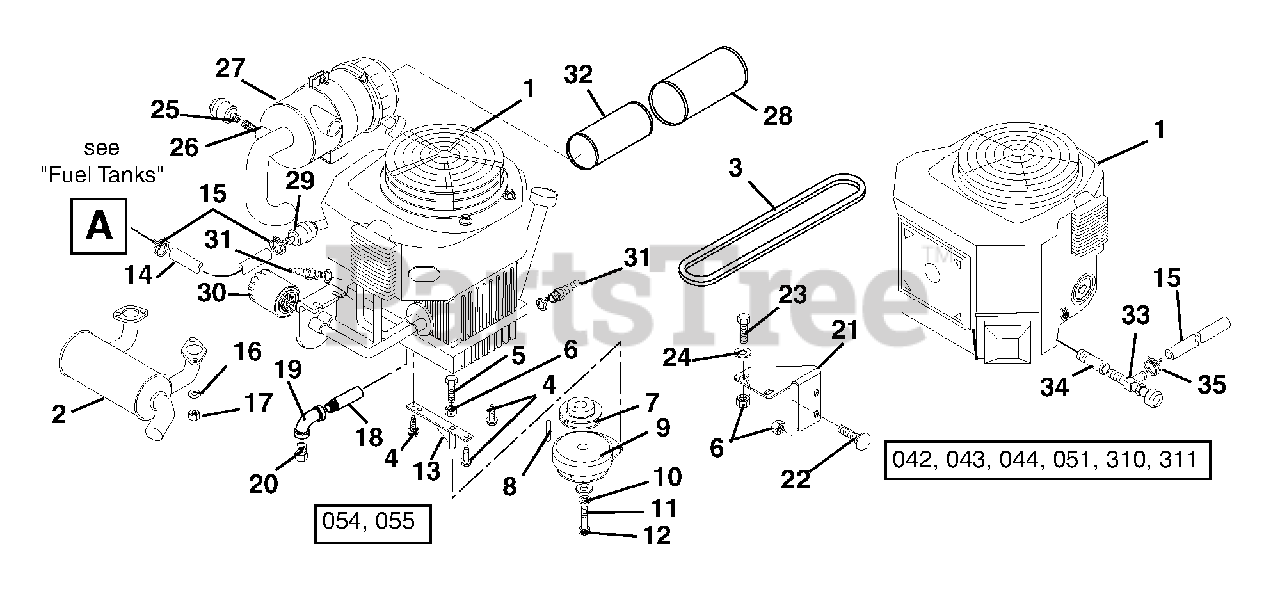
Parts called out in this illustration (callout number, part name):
1	Engine, Kohler, 25HP (054, 055)
1	Engine, Kawasaki 19HP (042, 310)
1	Engine, Kawasaki 21HP (043, 311)
1	Engine, Kawasaki 23HP (044, 051)
2	Muffler, Kohler (054, 055)
2	Muffler, Kawasaki (042, 043, 044, 051, 310, 311)
3	V-Belt HA 52 x .535 G48667
4	Screw, Tapping Hex Washer Head .38-16 x 1.00
5	Bolt, Hex .31-18 x 1.50 Grade 5
6	Nut, Locking Top Flange .31-18 (054, 055)
6	Nut, Locking Top Flang,e .31-18 (042, 043, 044, 051, 310, 311)
7	Pulley-V 4.00 x 1.125 with Key 1.42 Height
8	Key, Square .25 x .625 x .25 SAE 8630 OR SAE 1035
9	Clutch, Electric
10	Washer, Flat Steel .515 x 1.625 x .250
11	Washer, Locking .44 x .109
12	Bolt, Hex .44-20 x 2.50 Grade 5
13	Weldment, Clutch Anchor
14	Gas Line, Bulk .25 ID
15	Hose, Clamp
16	Washer, Lock .31 x .078 Regular
17	Nut, Hex M8-1.25
18	Nipple (054, 055)
19	Elbow .375-18 (054, 055)
20	Pipe Plug (054, 055)
21	Bracket, Oil Filter Mounting-Kohler (054, 055)
22	Bolt, Round Head Square Neck .31-18 x .62 (054, 055)
23	Bolt, Hex .31-18 x 1.00 Grade 5 (054, 055)
24	Washer, Flat Steel .38 x .875 x .083 (054, 055)
25	Filter Minder (054, 055)
26	Nipple, .125 NPT (054, 055)
27	Assembly, Air Cleaner
28	Filter, Outer Element
29	Fuel Filter, Kohler (054, 055)
29	Fuel Filter, Kawasaki (042, 043, 044, 051, 310, 311)
30	Oil Filter, Kohler (054, 055)
30	Oil Filter, Kawasaki (042, 043, 044, 051, 310, 311)
31	Spark Plug, Kohler (054, 055)
31	Spark Plug, Kawasaki (042, 043, 044, 051, 310, 311)
32	Filter, Inner Element
33	Cock, Oil Drain (042, 043, 044, 310, 311)
34	Adapter, Oil Drain (042, 043, 044, 310, 311)
35	Gas Line, Bulk .25" ID (042, 043, 044, 310, 311)
